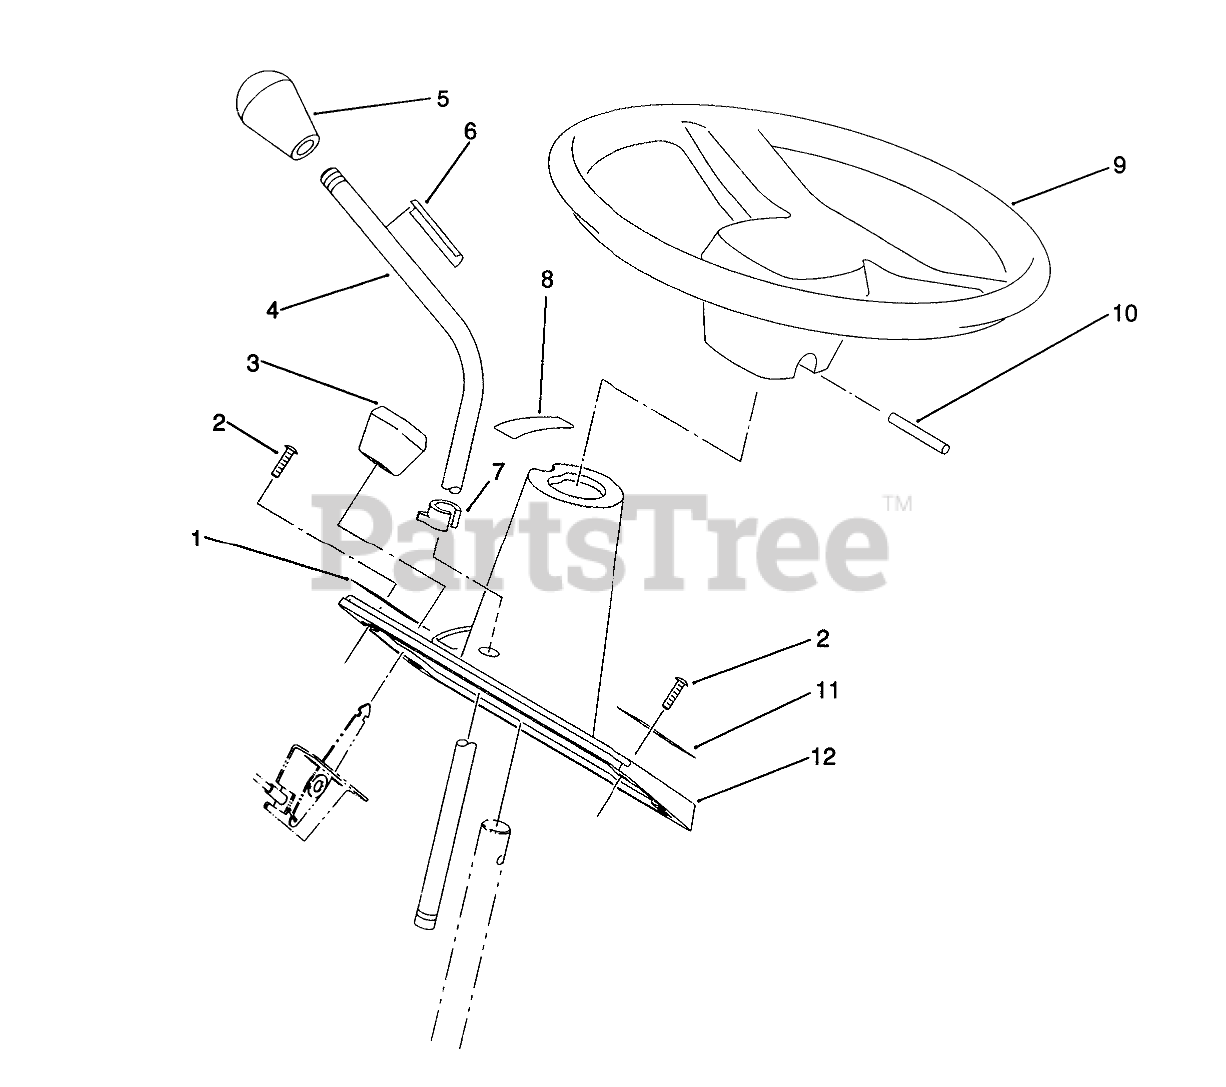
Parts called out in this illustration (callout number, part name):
1	DECAL-THROTTLE
2	SCREW
3	KNOB-CONTROL
4	ROD-SHIFT LEVER
6	DECAL-MOTION CONTROL
7	POINTER
8	Decal-5 Speed, Motion
9	STR'G-WHL 13" TORO
10	Pin-Roll
11	Decal-Height of Cut
12	CONSOLE
